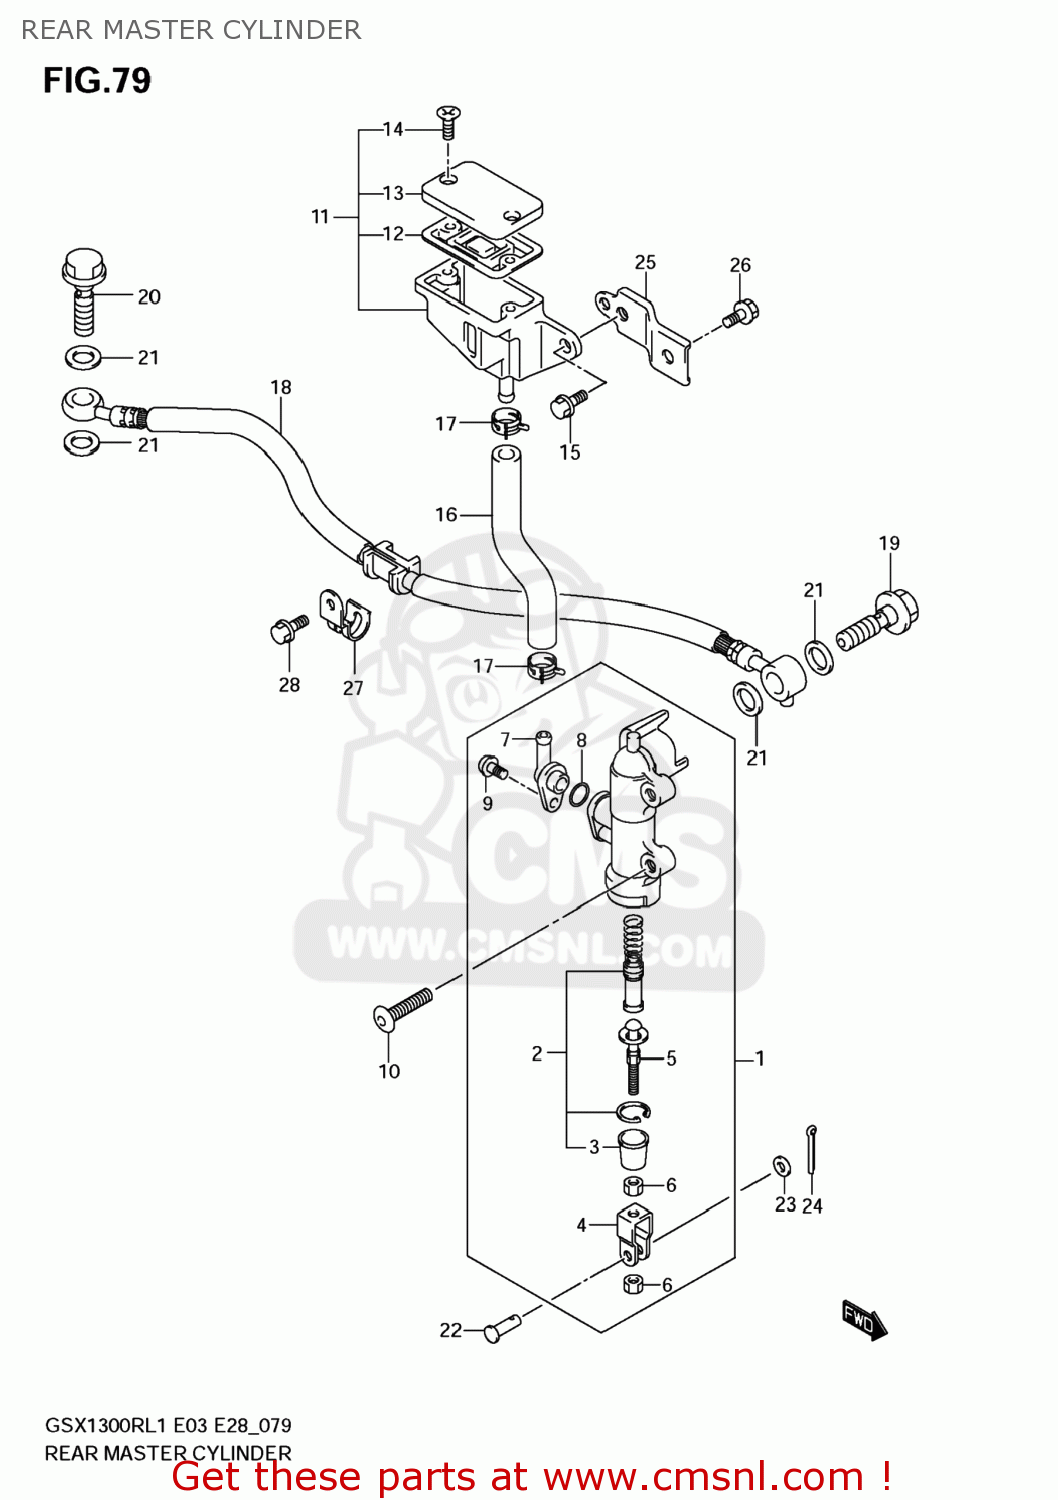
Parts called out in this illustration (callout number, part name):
1	CYLINDER ASSY,RR MASTER
2	PISTON/CUP SET
3	BOOT
4	YOKE
5	ROD,PUSH
6	NUT
7	CONNECTOR
8	O RING
9	SCREW
10	SCREW(6X20)
11	TANK ASSY,RR RESERVOIR
12	DIAPHRAGM
13	CAP
14	SCREW
15	BOLT
16	HOSE,RESERVOIR TANK
17	CLIP
18	HOSE,RR BRAKE
19	BOLT UNION
20	BOLT UNION
21	WASHER(10X15X1.5)
22	PIN(6X18.2)
23	WASHER
24	PIN
25	BRACKET,RR RESERVOIR TANK
26	BOLT
27	CLAMP,RR BRAKE HOSE
28	BOLT
